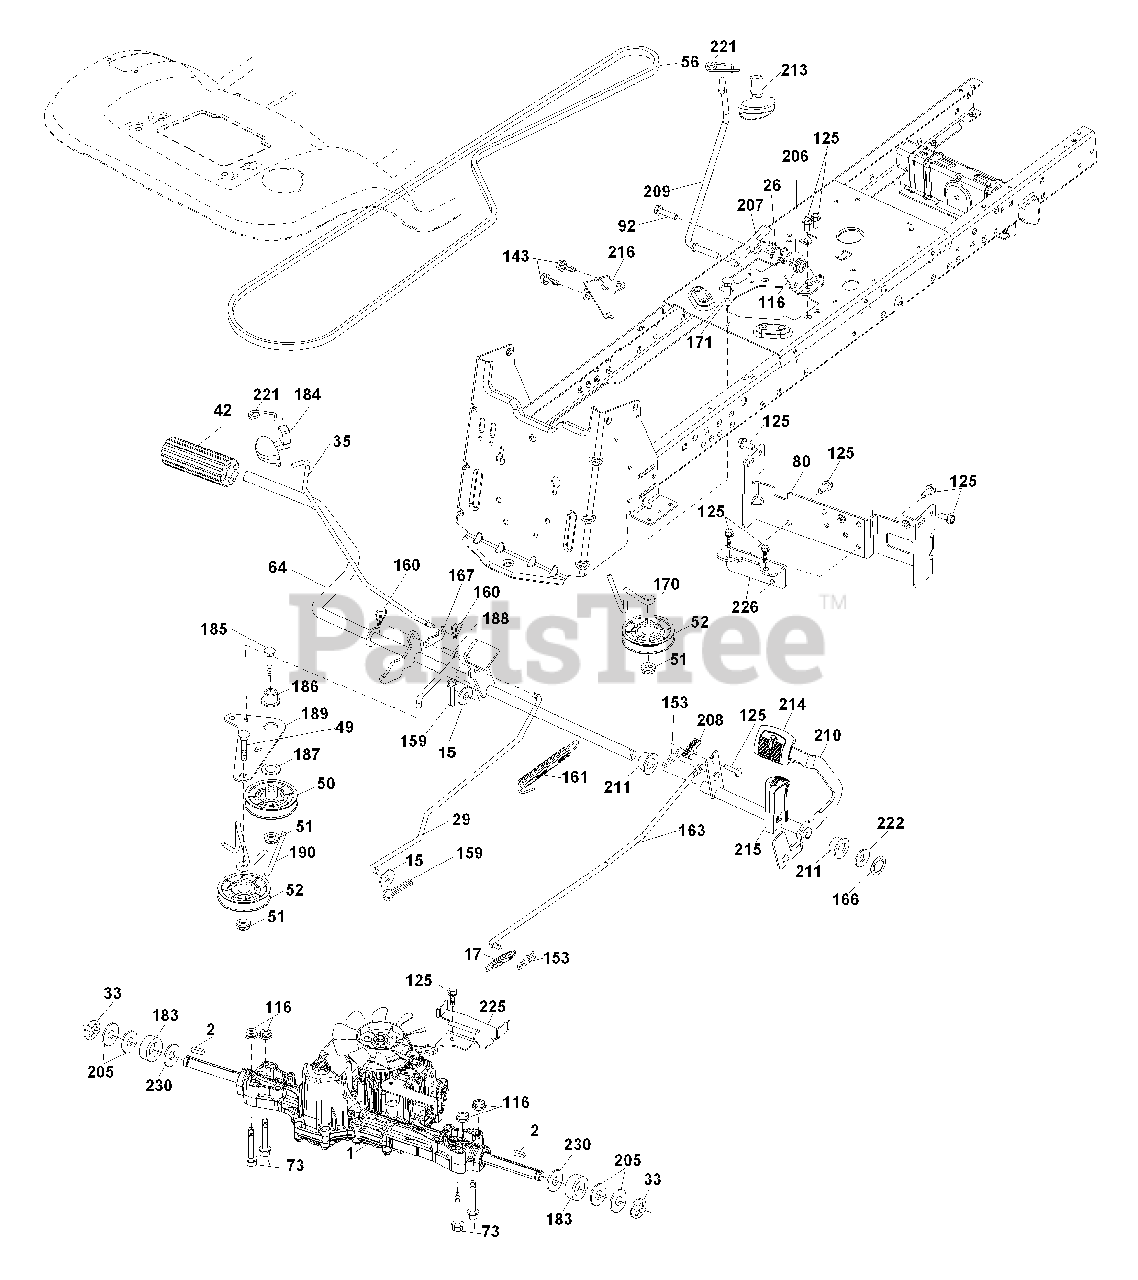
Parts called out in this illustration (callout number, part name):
1	Transaxle, TUFFTORQ K46
15	Washer 13/32 x 13/16 x 16 Ga.
17	Spring, Brake
26	Spring Return Cruise
29	Rod, Brake
35	Rod, Brake, Park
42	Cover, Foot Pedal
50	Pulley Idler Flat
51	Lock Nut 3/8-16
52	Idler V-Groove 910" Offset
56	V-Belt, Drive
64	Shaft Asm. Pedal Brake Control
80	Strap Torque
92	Bolt Fin Hex 5/16-18 unc x 1.25
116	Nut Lock Hex Flange 5/16-18
125	Screw 5/16-18 x 3/4
143	Screw 5/16-18 x 1/2
153	Retainer Spring
159	Pin Cotter 1/8 x 3/4
160	Retainer Clip
161	Spring, Return, Clutch
163	Rod Pedal Control
166	Nut Push
167	Latch Brake Parking
170	Keeper Belt Centerspan
171	Bolt RDHD SQNK 3/8-16UNC x 2
183	Spacer Split
184	Handle Parking Brake
185	Bolt Rdhd Sqnk 3/8-16 x 2-1/2
186	Spacer Retainer
187	Washer
188	Link Clutch Ground Drive
189	Bellcrank Ground Drive
190	Keeper Bellcrank Ground Drive
206	Bracket Mount Latch Cruise
207	Latch Control Cruise
208	Gear Sector Control Cruise
209	Rod Control Cruise
210	Rocker Asm. Pedal Control
211	Bearing Nylon
213	Knob Control Cruise
214	Pedal Forward
215	Pedal Reverse
216	Bracket Pulley Idler
221	Retainer Spring Clip Handle
222	Washer 21/32 x 1-1/4 x 10 Ga.
225	Keeper Belt Trans.
226	Bracket Mount Touque
230	Washer Hardened
